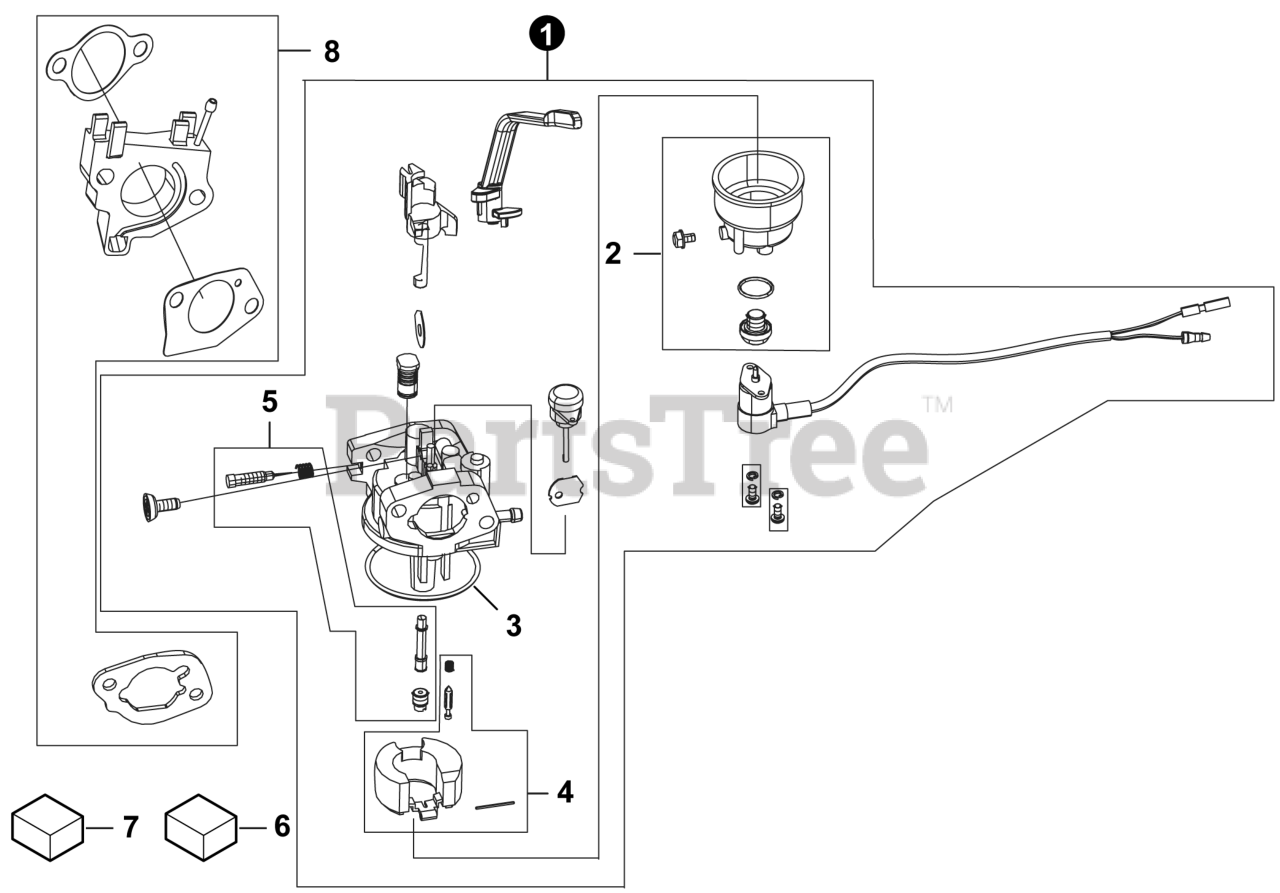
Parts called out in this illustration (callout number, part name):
1	CARBURETOR ASSY.
2	KIT, BOWL
3	GASKET, CARB BOWL
4	KIT, FLOAT
5	KIT, MAIN JET
6	KIT, EG-10000 HIGH ALTITUDE JET 3-6K
7	KIT, EG-10000 HIGH ALTITUDE JET 6-8K
8	GASKET SET, INTAKE
